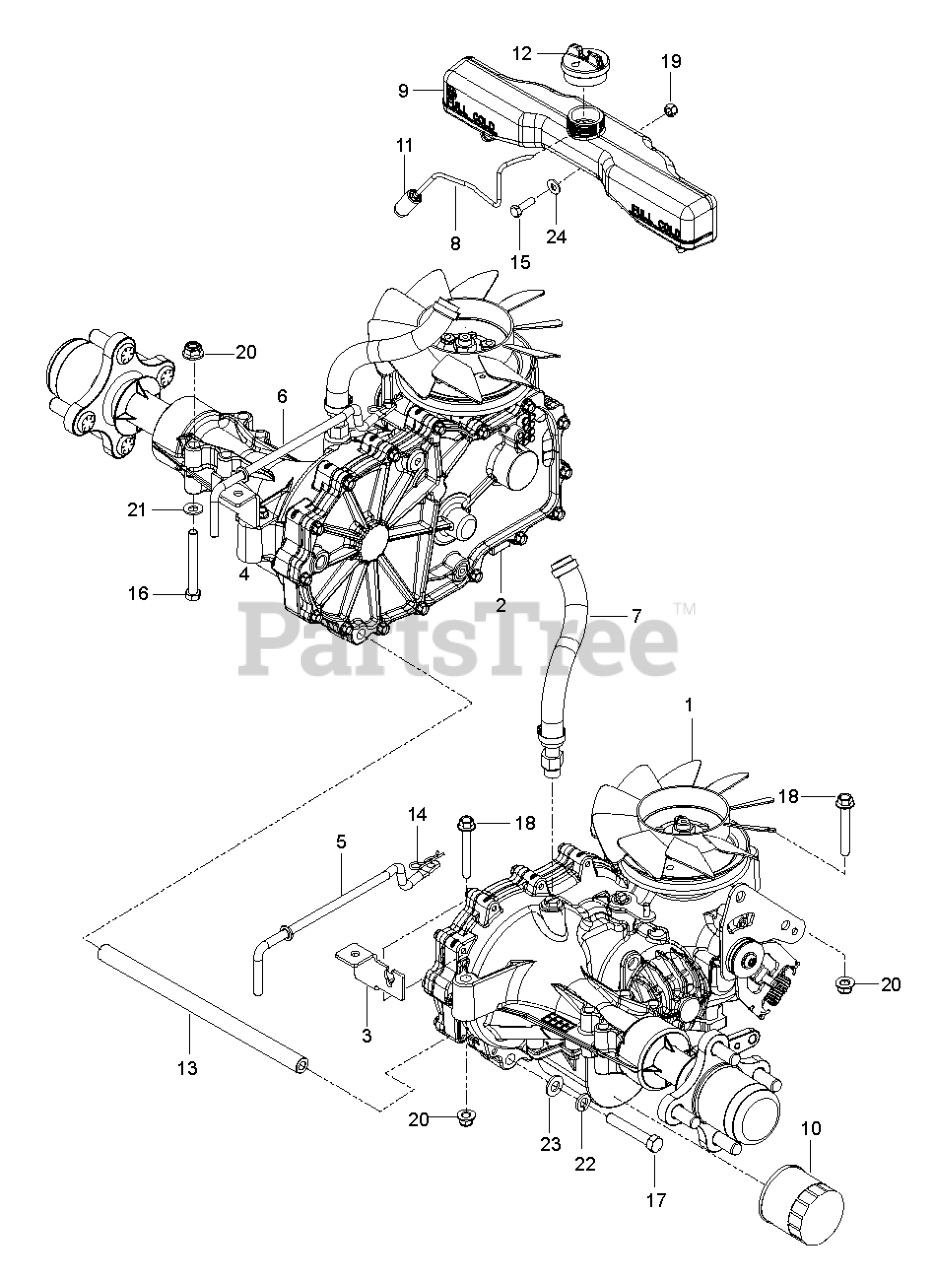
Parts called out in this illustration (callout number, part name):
1	HG_TRANS ZT-3100 LT
2	HG_TRANS ZT-3100 RT
3	BRACKET.TRANS.LT.BLACK
4	BRACKET, TRANS, RT BLACK
7	HOSE ASSY, EXPANSION
9	TANK EXPANSION W/CAP
10	HG_FILTER, ZT4800 52114
11	FUEL PICK-UP ASSY
12	CAP EXPANSION W/SEAL
19	NUT HEXAGON 1/4-20 ST ZPB
20	NUT HEXAGON FLANGE 5/16-18 ST
21	WASHER 11/32 X 11/16 X 14 GA T
23	WASHER PLAIN WASHER 3/8 X 0.08
